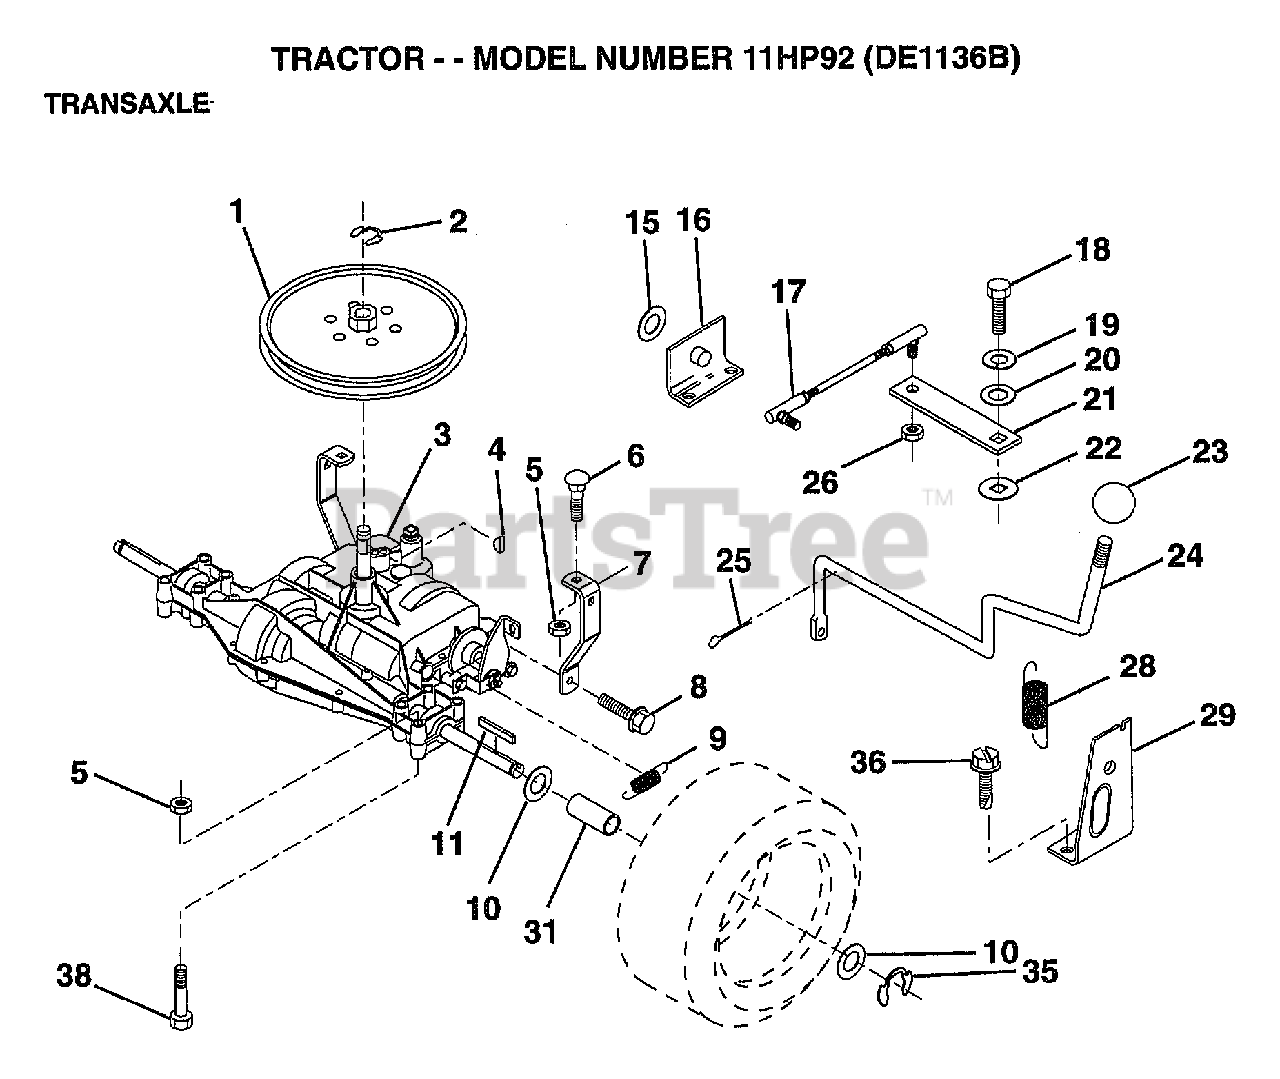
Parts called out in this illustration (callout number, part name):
1	PULLEY
6	BOLT
7	"STRAP,TORQUE"
8	SCREW
9	SPRING.BRAKE.RETU
10	WASHER
11	SQUARE KEY
16	SUPPORT HANDLE SHIFT LH
17	LINK SHIFT
18	BOLT.1/4-28.W/PAT
19	LOCKWASHER
20	WASHER LT
22	WASH-SHFT PLT LT
23	KNOB T (1/2-HOLE)
24	"ROD,SHIFT"
25	PIN COTTER 1/8
26	NUT.LOCK.5/16-24
28	"SPRING,EXT"
29	"SUPT,HDLE RH"
31	SPACER AXLE
35	E-RING LT
36	SCREW
38	BOLT.HEX.FLGHD
